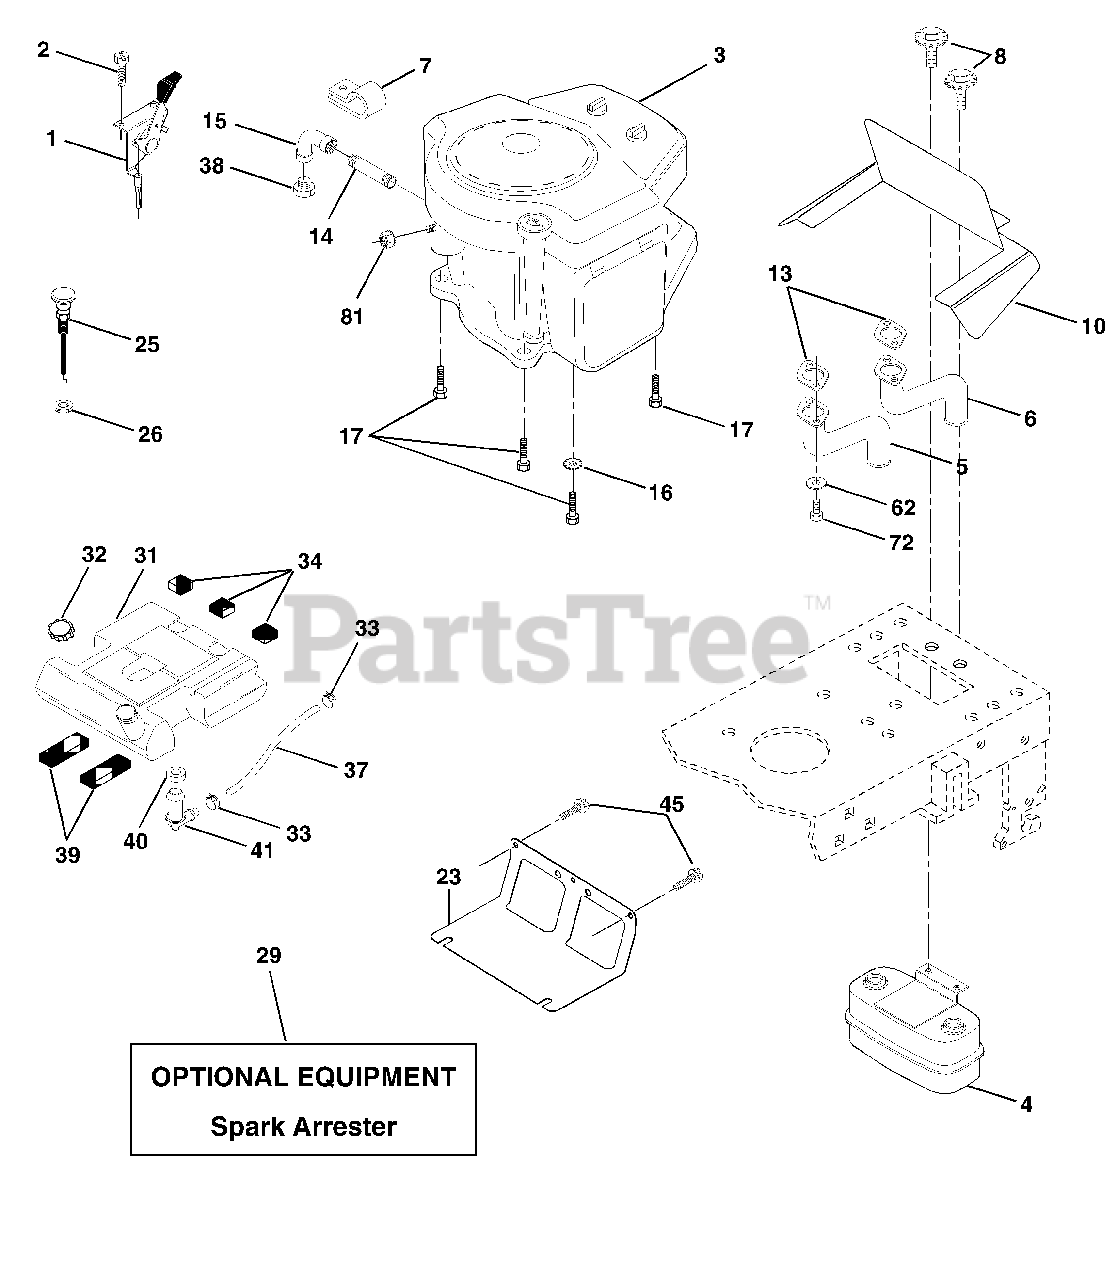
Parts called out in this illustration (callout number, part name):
1	Control, Throttle
2	Screw, Hex Head, Thread Cutting 1/4-20 x 5/8
4	Muffler
5	Tube, Manifold, LH
6	Tube, Manifold, RH
7	Clip Insulated
8	Bolt 5/16-18 UNC x 3/4 w/Sems
10	Shield, Browning
13	Muffler Gasket
14	Nipple, Pipe 3/8 NPT x 4-1/2
15	Elbow, Standard 90° 3/8-18 NPT
16	Washer, Lock, External Tooth 3/8
17	Screw Thdrol 3/8-16 x 1-1/2
23	Shield, Browning / Debris Guard
25	Choke Control
26	Nut, Keps 3/8-24 UNF
29	Kit, Spark Arrestor
31	Tank Fuel 3 50 Rear
32	Cap Asm Fuel W/sym Vented
33	Clamp, Hose
34	Pad, Spacer
37	Line, Fuel
38	Plug, Oil Drain
39	Pad, Idler
40	Bushing
41	Stem, Fuel Tank
45	Screw Hex wsh Thdrol 3/8-16 x 3/4
62	Washer Lock 5/16
72	Screw Hex Hd Cap 5/16-18 x 3/4
81	Nut Keps Hex 1/4-20 Unc
